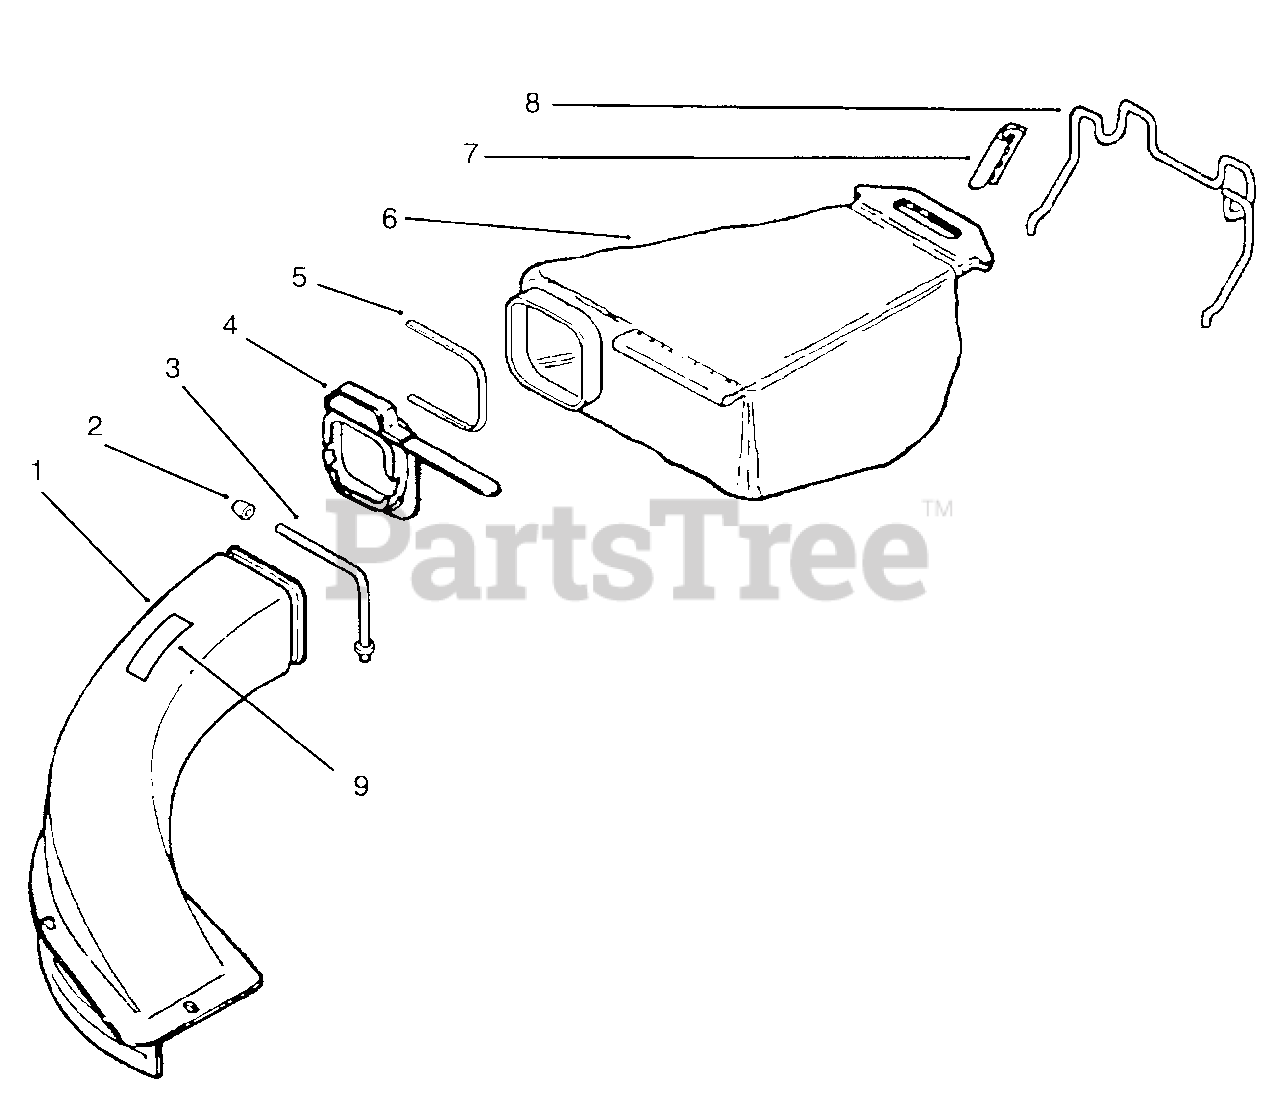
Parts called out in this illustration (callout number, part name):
1	Chute & Support Assembly (Incl. Ref.# 2,3 & 9)
2	Nut-Cap
3	Chute Support
4	Adaptor Assembly
5	Tie Strap
6	Bag Assembly
7	Hanger Clamp
8	Wide Hanger 613463 Narrow Hanger
9	Decal-Danger
